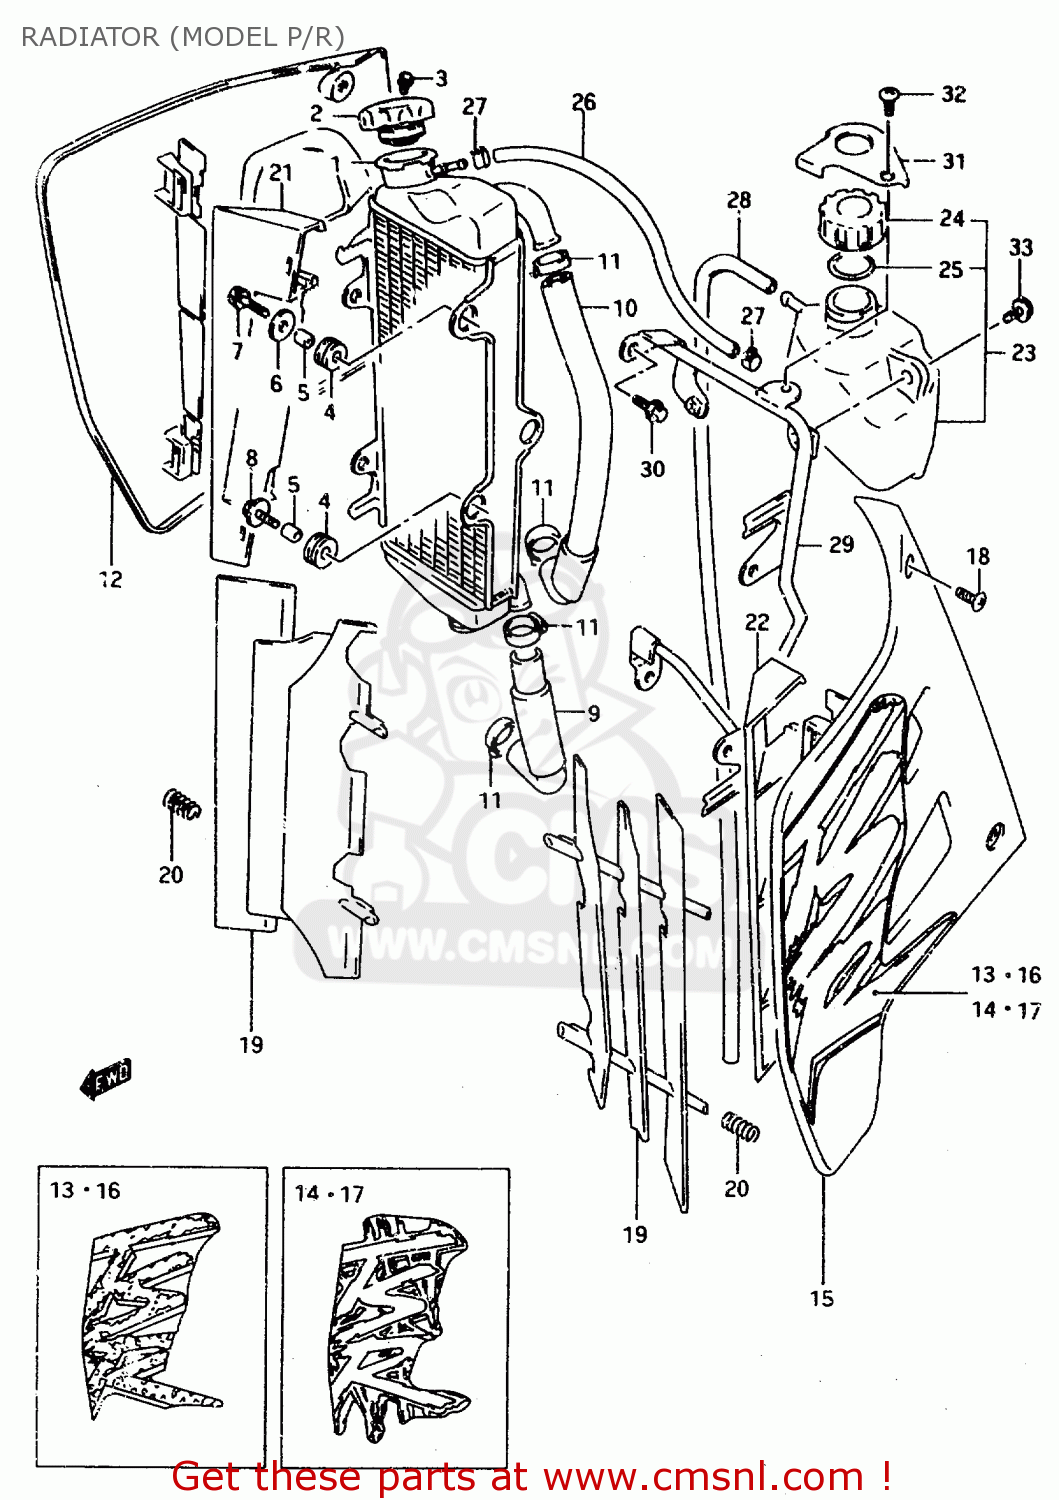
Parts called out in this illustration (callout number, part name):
1	RADIATOR,WATER
2	CAP, RADIATOR (0.9)
3	SCREW,RADIATOR CAP
4	CUSHION,RADIATOR LWR
5	SPACER(6.5X10.5X12)
6	WASHER
7	BOLT
8	BOLT(6X20)
9	HOSE,RADIATOR INLET
10	HOSE,RADIATOR OUTLET
11	CLAMP
12	COVER,RADIATOR,R(YELLOW)
13	TAPE, RADIATOR COVER,RH
14	TAPE,RADIATOR COVER,R
15	COVER,RADIATOR,L(YELLOW)
16	TAPE, RADIATOR COVER,LH
17	TAPE,RADIATOR COVER,L
18	SCREW
19	LOUVER,RADIATOR
20	SPRING
21	GUARD,RADIATOR LOUVER,R
22	TAPE, RADIATOR COVER,LH
23	TAPE, RADIATOR COVER,LH
24	SCREW
25	LOUVER,RADIATOR
26	SPRING
27	CLIP
28	HOSE
29	TANK ASSY,RESERVOIR
30	BOLT
31	PLATE,RESERVE TANK CAP
32	SCREW
33	CLIP
34	HOSE
35	HOLDER, RESERVE TANK
36	BOLT
37	PLATE,RESERVE TANK CAP
38	SCREW
39	SCREW(6X16)
40	SWITCH ASSY,WATER TEMP
